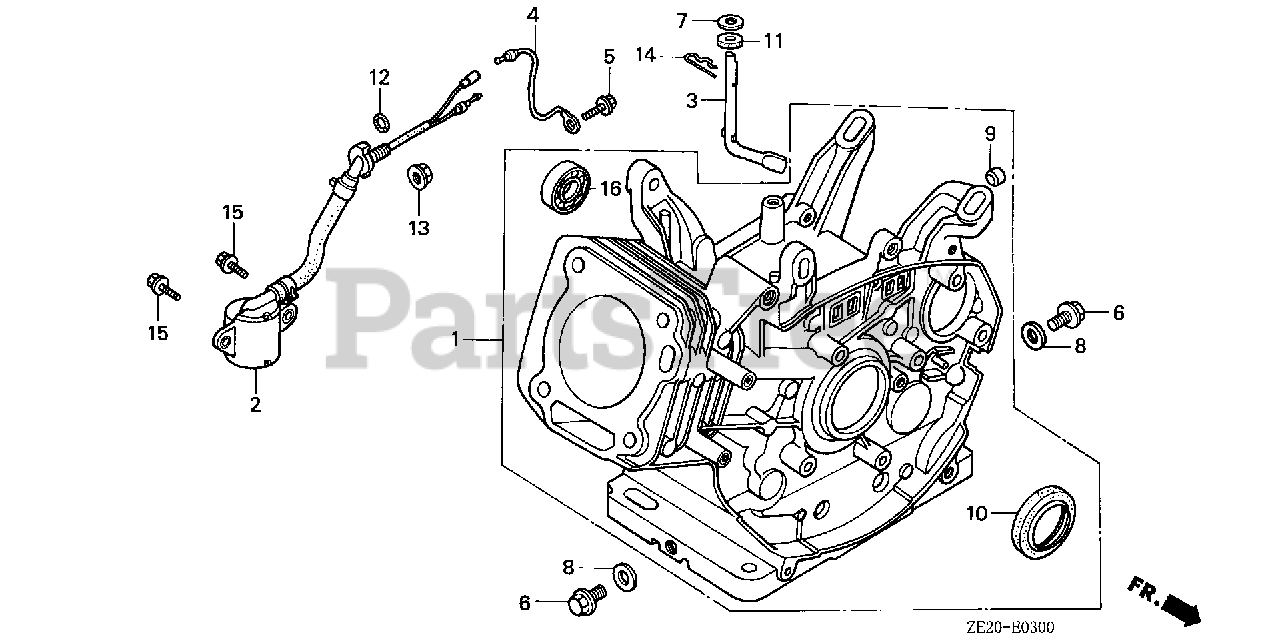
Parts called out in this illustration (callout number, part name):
1	CYLINDER ASSY. (BALANCER+ALERT)
2	SWITCH ASSY., OIL LEVEL
3	SHAFT, GOVERNOR ARM
6	BOLT, DRAIN PLUG (12X15)
7	WASHER (8.2X17X0.8)
8	WASHER, DRAIN PLUG (12MM)
10	OIL SEAL (30X46X8)
11	OIL SEAL (8X14X5)
12	O-RING (14MM) (ARAI)
12	O-RING (14MM) (NOK)
13	NUT, FLANGE (10MM)
14	PIN, LOCK (8MM)
15	BOLT, FLANGE (6X12)
16	BEARING, RADIAL BALL (6202)
